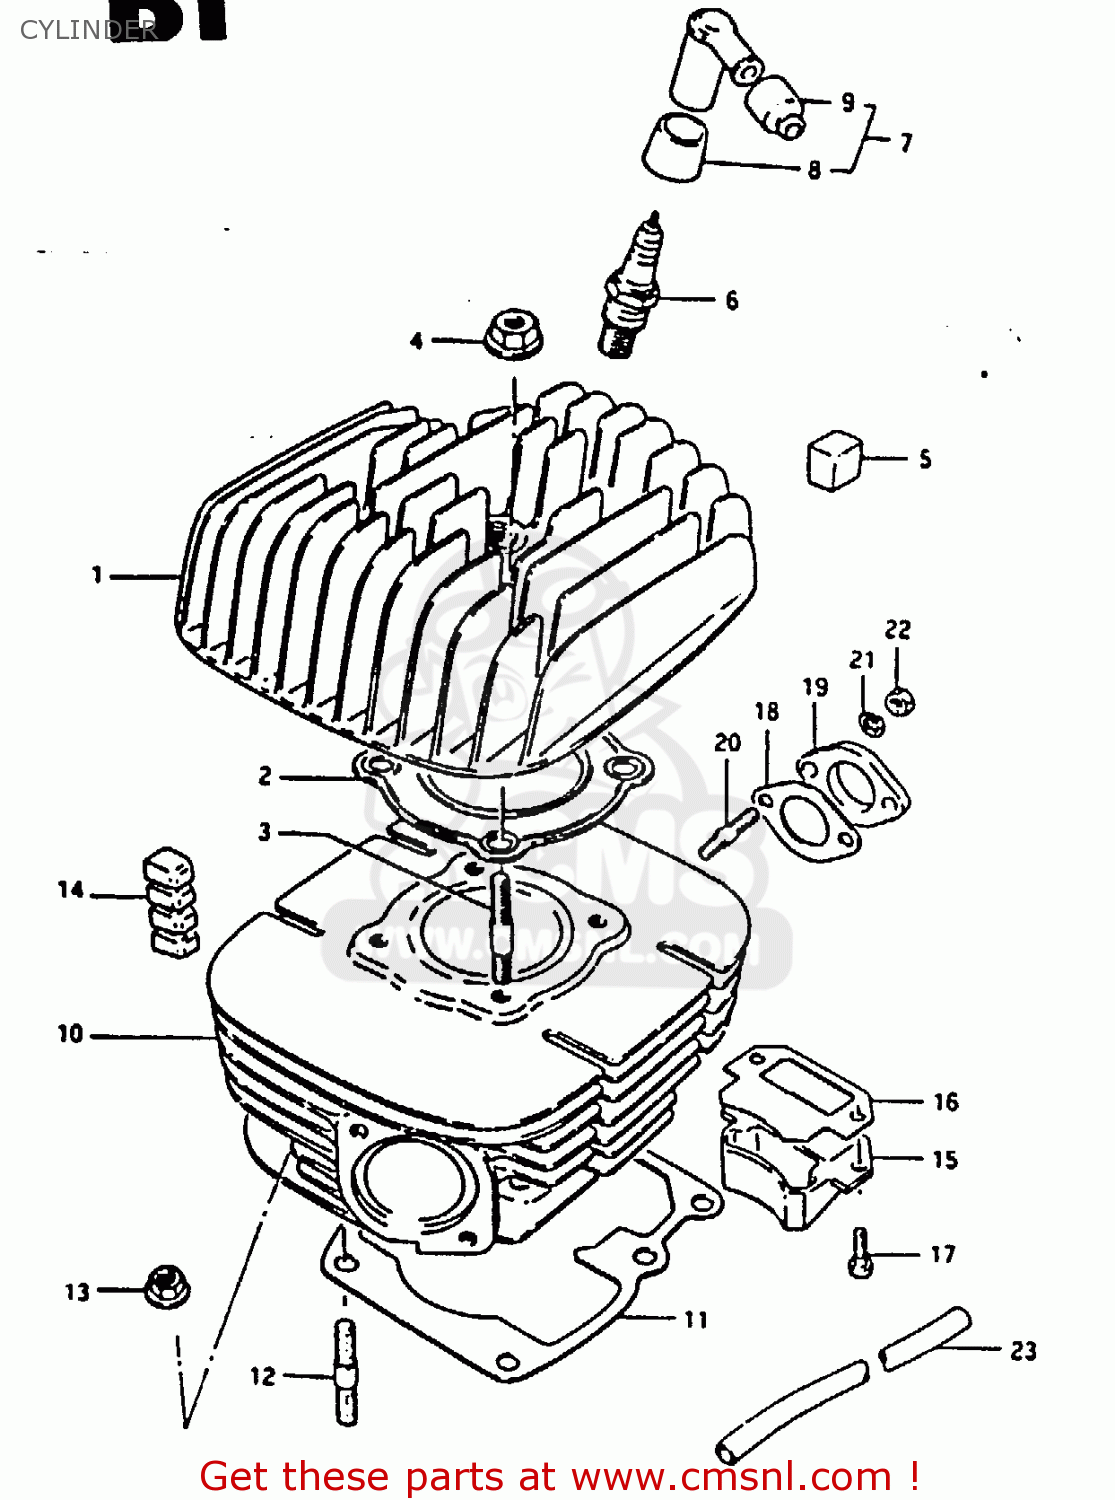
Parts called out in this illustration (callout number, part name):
1	HEAD,CYLINDER
2	GASKET,CYLINDER HEAD (MCA)
3	STUD BOLT
4	NUT
5	PAD,CYLINDER
6	PLUG,SPARK
7	CAP,SPARK PLUG
8	SEAL,SPARK PLUG
9	SEAL,SPARK PLU
10	CYLINDER
11	GASKET,CYLINDER (MCA)
12	STUD 8X25
13	NUT
14	PAD,CYLINDER
15	VALVE ASSEMBLY,REED
16	GASKET,REED VALVE (MCA)
17	SCREW
18	GASKET,CARBURETOR (MCA)
19	INSULATOR,CARBURETOR
20	STUD BOLT
21	LOCK WASHER
22	NUT
23	HOSE
